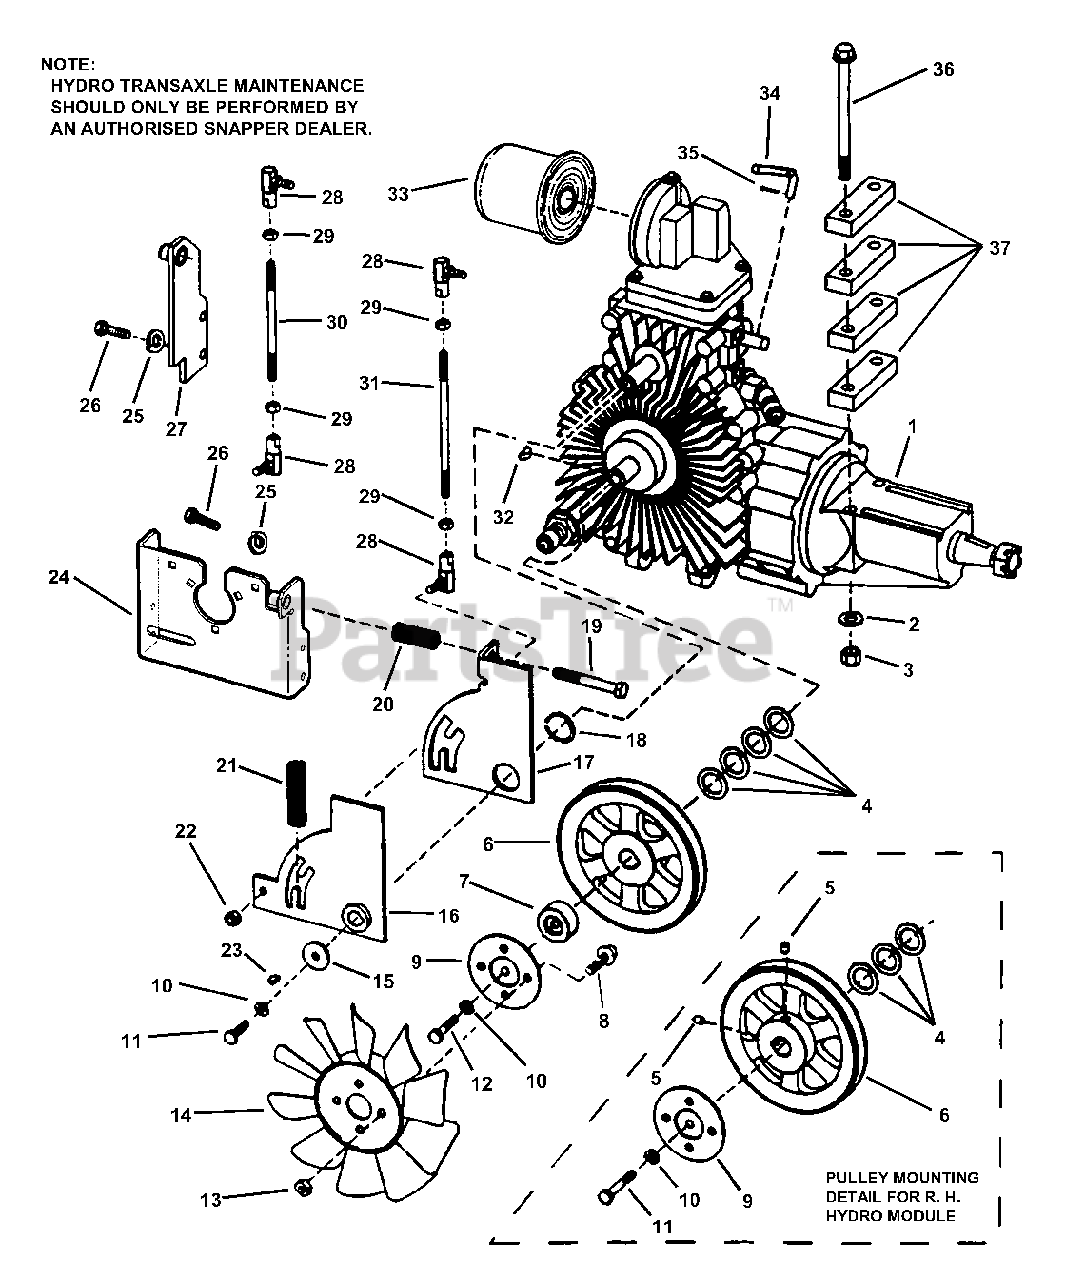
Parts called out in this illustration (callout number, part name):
1	ASSEMBLY, Transaxle 771B (L.H.) Side
2	WASHER, 3/8" Flat
3	NUT, 3/8-16 HEX NYLON LOCK
4	WASHER, 3/4 I.D. x 1-1/8" O.D. Flat
5	SET SCREW, 5/16-18 x 5/16" Hex Recess
6	PULLEY, Transmission 4.95" Diameter
7	SPACER/ADAPTER, Fan
8	SCREW, 1/4-20 x 5/8", Hex Flange Lock, Grade 5
9	SPACER, Fan
10	WASHER, 1/4 Split Lock
11	SCREW, 1/4-20 x 1-1/4", Hex Head Cap
12	SCREW, 1/4-20 x 2", Hex Head Cap, Grade 5
13	NUT, 1/4-20 HEX NYLON LOCK
14	FAN, Blade 7" Dia.
15	WASHER, 1/4 I.D. x 1" O.D.
16	CAM, Neutral Return (Weldment)
17	PLATE, Neutral Adjust
18	RETAINING RING, 1" External
19	BOLT, 5/16-18 X 2-1/2" GD5 YZ
20	SPRING, Neutral Return Adjust
21	SPRING, Neutral Return
22	NUT, 1/4-28, Hex Nyloc
23	WOODRUFF KEY, #404
24	ASSY, Driveshaft Bracket
25	WASHER, 21/64" Split Lock
26	SCREW, 5/16-18 x 7/8", Hex Head Cap
27	PLATE, Neutral Return (Weldment)
28	BALL-JOINT
29	NUT, 1/4-28 Hex, Grade 5 or B
30	ROD, Threaded 1/4-28 x 6-5/8"
31	ROD, Threaded 1/4-28 x 5-3/8"
32	WOODRUFF KEY, #605
33	FILTER, Oil (Eaton)
34	ROD, Roll Release
35	COTTER-PIN, 1/16 x 1/2"
36	BOLT, 3/8-16 x 4-3/4" Grade 5
37	SPACER, Eaton Transaxle
